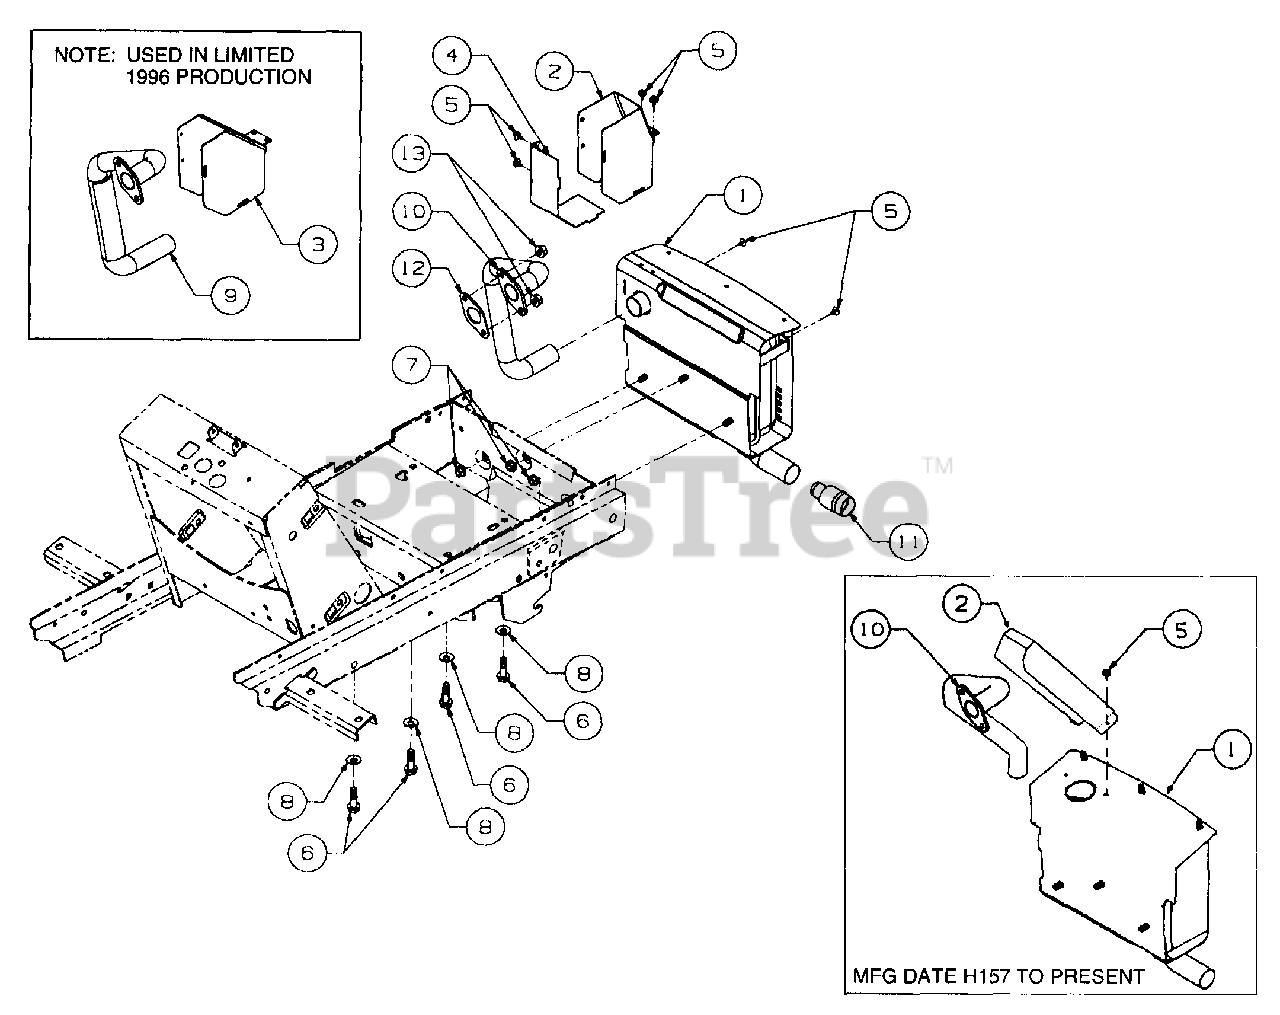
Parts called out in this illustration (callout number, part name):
1	Muffler Assy
2	Shield, Exh.
3	Shield, Exh.
4	Shield, Exhaust Tube Rear
5	Screw, Hex Wash Hd Tapp, #10-16 x .38
6	Screw, Engine Mounting, 3/8-16 x 1.25
7	Nut, Hex Flange Lock, 5/16-18
8	Washer, Bell, .380 x .88 x .062
9	Tube, Exhaust, w/Attached Heat Baffle
10	Tube, Exh.
11	Arrestor, Spark
12	Gasket, Exhaust
13	Nut, Exhaust, M8 x 1.25
